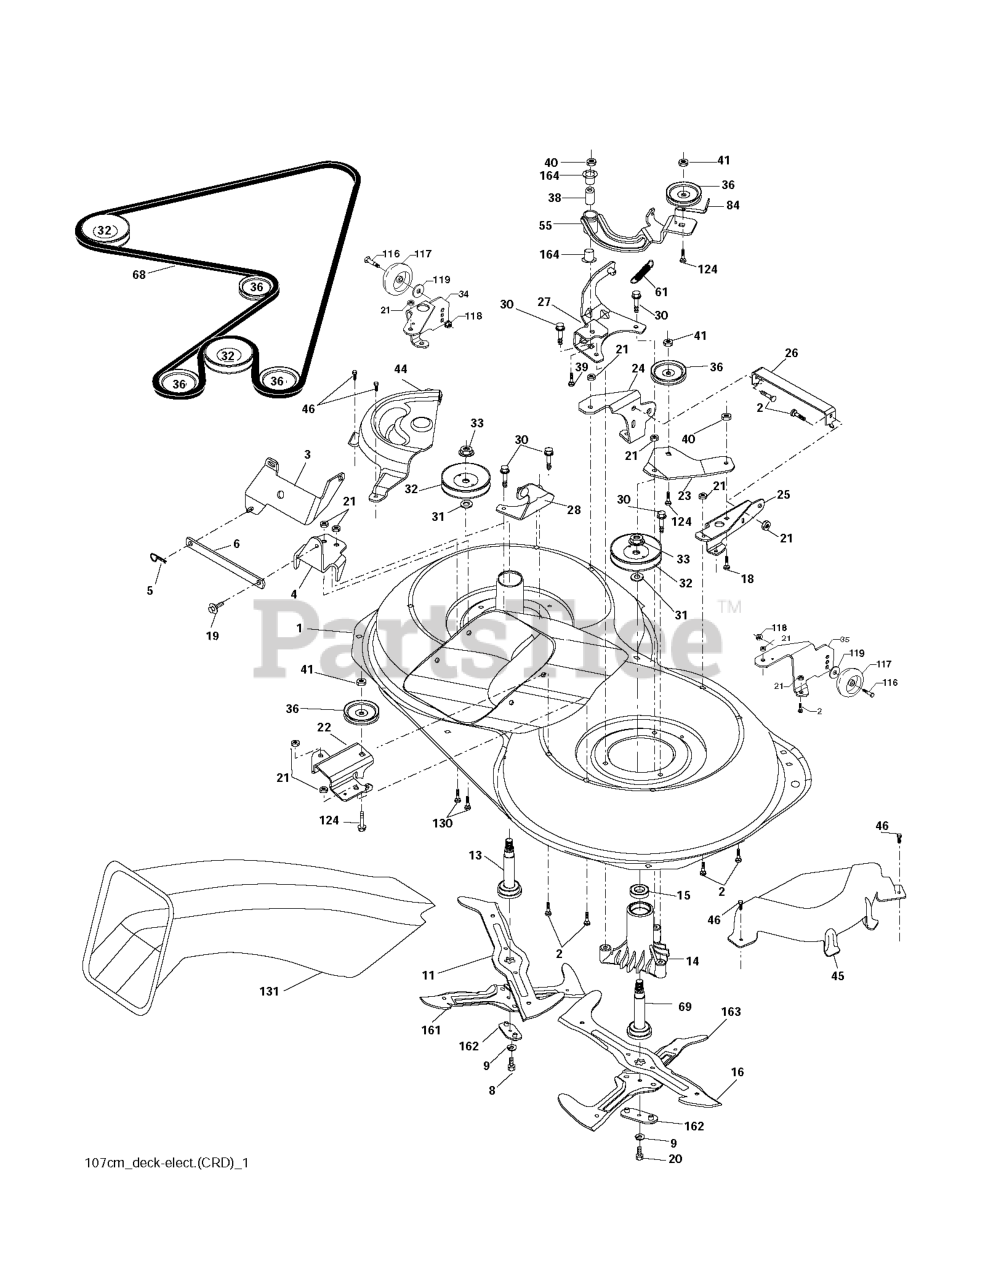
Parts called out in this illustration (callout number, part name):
1	Housing Asm. Mower 107 CRD
2	RP BOLT 5/16-18 X3/4 ZN/YEL GR
5	RETAINER-SPRNG RB
6	BAR.SWAY.92.CRD
8	BOLT.3/8-24X1.25 GR8
9	LOCKWASHER
11	BLADE.3N1.LH.CRD
13	SHAFT ASM VENT
14	HOUSING.MANDREL.VENTED (MACHD)
16	BLADE.3N1.RH.CRD
19	BOLT SHD 5/16-18
20	BOLT.3/8-24X1.25GR8. LHTHRD
21	LOCKNUT
22	BRACKET.IDLER.RR.107.CRD
24	BRACKET
25	BRACKET RF
26	SUPPORT
28	BRACKET
30	SCREW, WASHER HEAD
31	WASHER.SPACER.MANDREL
32	PULLEY.MANDREL.4.80 PD.2006
33	NUT.FLANGE.LOCK.TOP
34	BRACKET
35	BRACKET
36	PULLEY.IDLER.4.25
41	NUT LOCK FLG 3/8-16 UNC
45	COVER.MANDREL.RH.CRD
46	SCREW.1/4-20X5/8
55	ARM.IDLER.107.CRD
61	SPRING
68	HEX-BELT 107 MOWER
69	SHAFT.ASM.W/LWR.BRG.RH.THREAD
84	KEEPER, BELT IDLER
116	BOLT.SHOULDER.3/8-16X3-5/8.
117	RP WHEEL. GUAGE RALLY
118	NUT LOCK FLG 3/8-16 UNC
119	WASHER
124	BOLT.3/8-16X1.50
130	BOLT.CARR.SQNK.5/16-18UNC.X3/4
131	CHUTE BAGGER
163	BLADE.CROSS.RH.CRD.107
164	BRNG T
